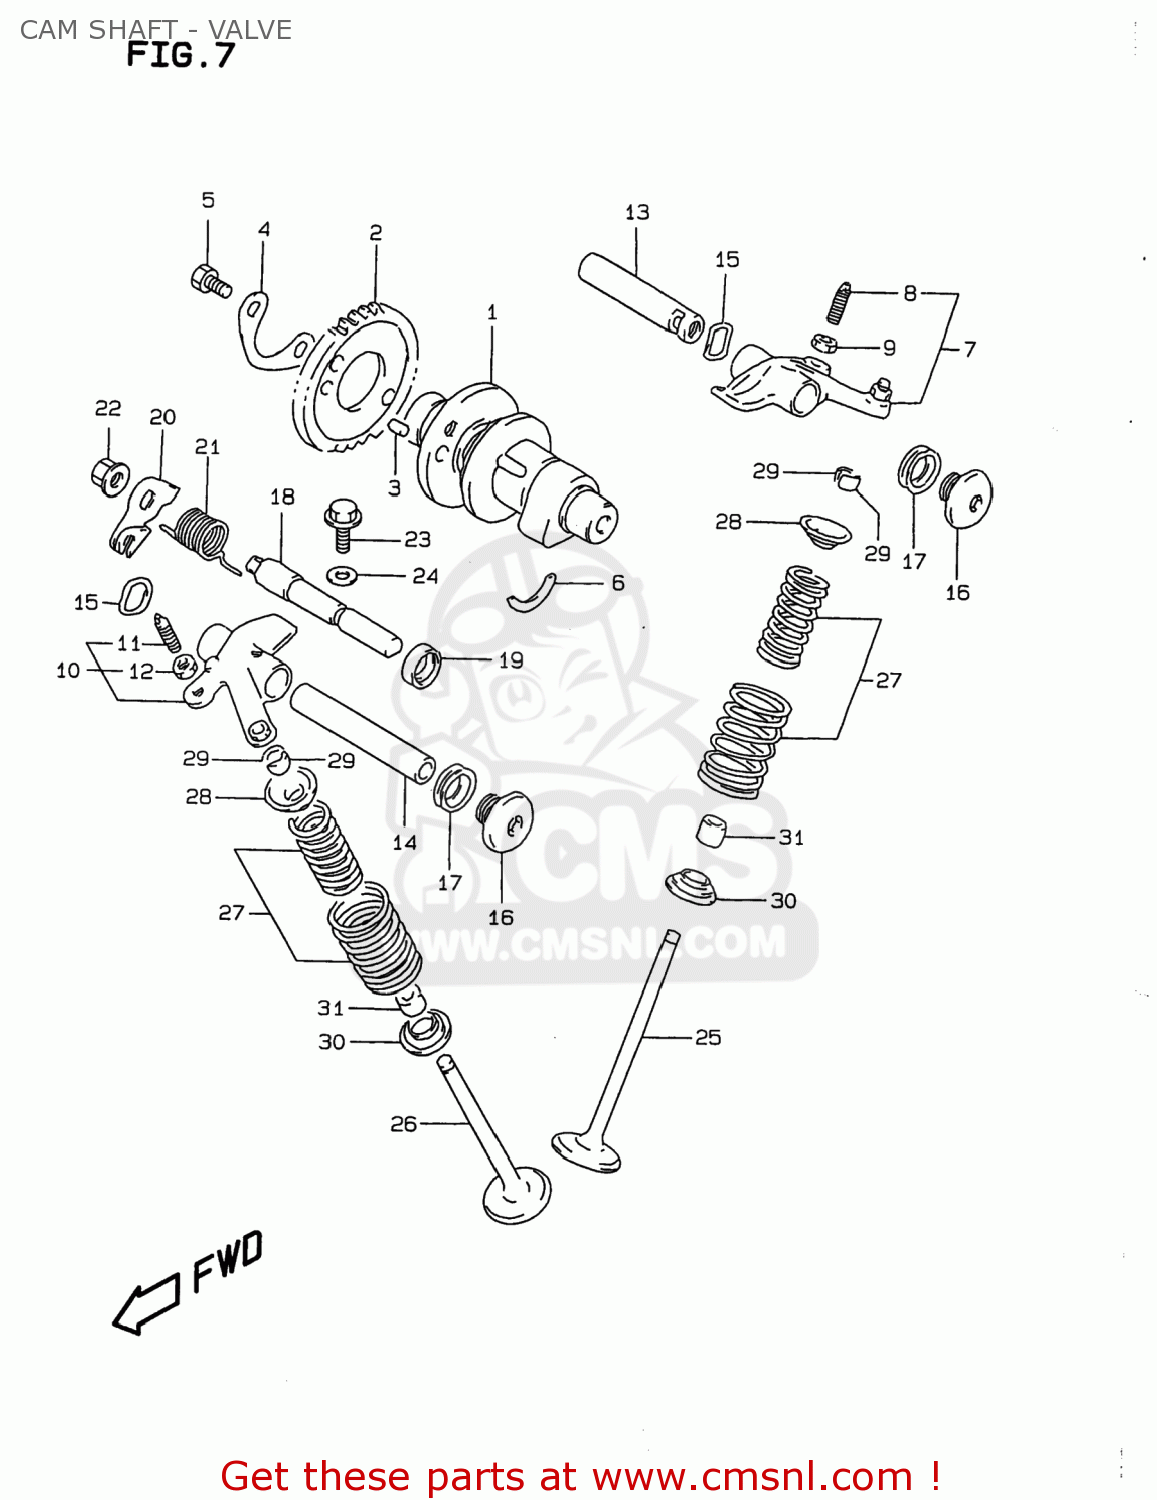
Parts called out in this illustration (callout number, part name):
1	CAMSHAFT COMP
2	SPROCKET,CAMSHAFT
3	PIN(5X8)
4	WASHER,SPROCKET
5	BOLT(6X10.5)
6	C RING
7	ARM,VALVE ROCKER,INTAKE
8	SCREW,TAPPET ADJUSTING
9	NUT,TAPPET ADJUSTING
10	ARM,VALVE ROCKER EXHAUST
11	SCREW,TAPPET ADJUSTING
12	NUT,TAPPET ADJUSTING
13	SHAFT,VALVE ROCKER ARM INTAKE
14	SHAFT,VALVE ROCKER ARM EXHAUST
15	WASHER
16	PLUG,14X12
17	GASKET(13.8X18.8X4.8) (NAS)
18	SHAFT,DECOMP
19	SEAL,OIL(10X17X6)
20	LEVER,DECOMPRESSION SHAFT
21	SPRING
22	NUT
23	BOLT
24	GASKET(6.4X11.5X0.8) (NAS)
25	VALVE,INTAKE
26	VALVE,EXHAUST
27	SPRING SET,VALVE
28	RETAINER,VALVE SPRING
29	COTTER VALVE
30	SEAT,VALVE SPRING
31	SEAL,OIL(5X10X9.7)
